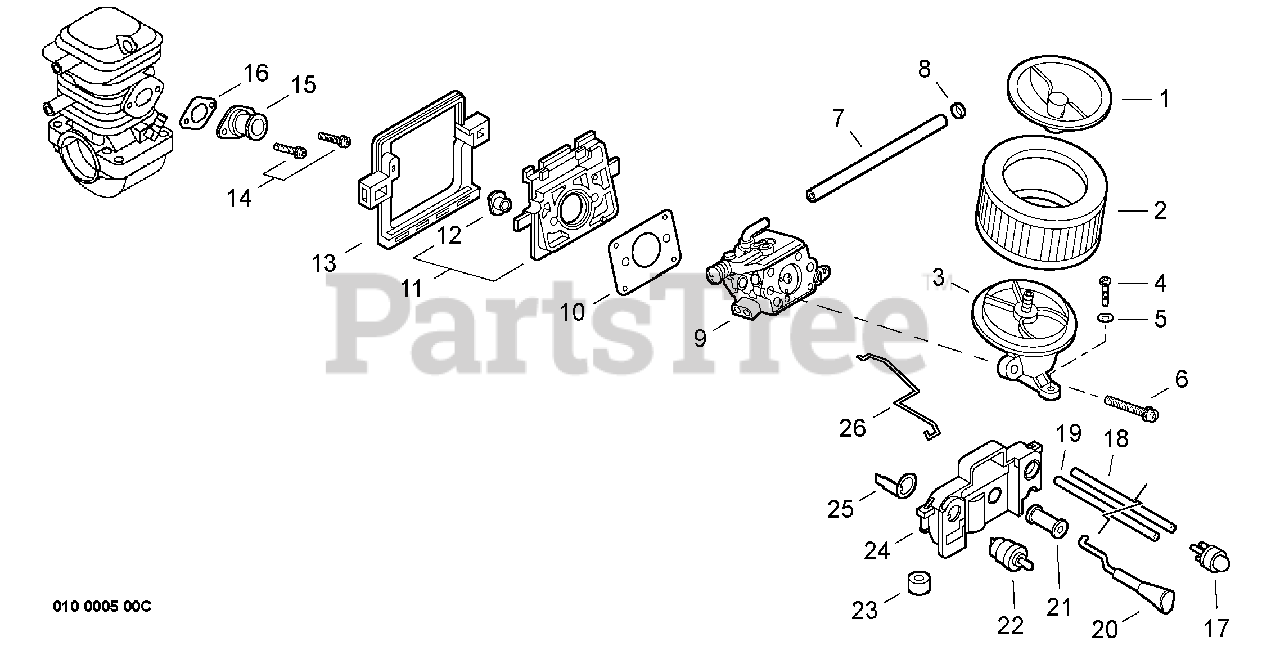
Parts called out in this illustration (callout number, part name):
1	COVER, AIR FILTER
2	FILTER, AIR
3	ADAPTOR, INTAKE
4	SCREW - 5X20 -- TAPPING
5	WASHER - 5
6	SCREW - 5X50
7	PIPE - 2.4X6X105 -- BLACK
8	CLIP - 6
9	CARBURETOR WT-906A
10	GASKET, INTAKE
11	INSULATOR KIT
13	CUSHION
14	SCREW - 5X14
15	ADAPTOR, INTAKE
16	GASKET, INTAKE
17	PUMP, PURGE
18	PIPE - 2.4X5X200 -- BLACK
19	PIPE - 2.4X5X105 -- BLACK
20	ROD, CHOKE
21	GROMMET
22	IGNITION SWITCH ASSY
24	BRACKET, SWITCH
25	TERMINAL - GROUND
26	ROD, THROTTLE
